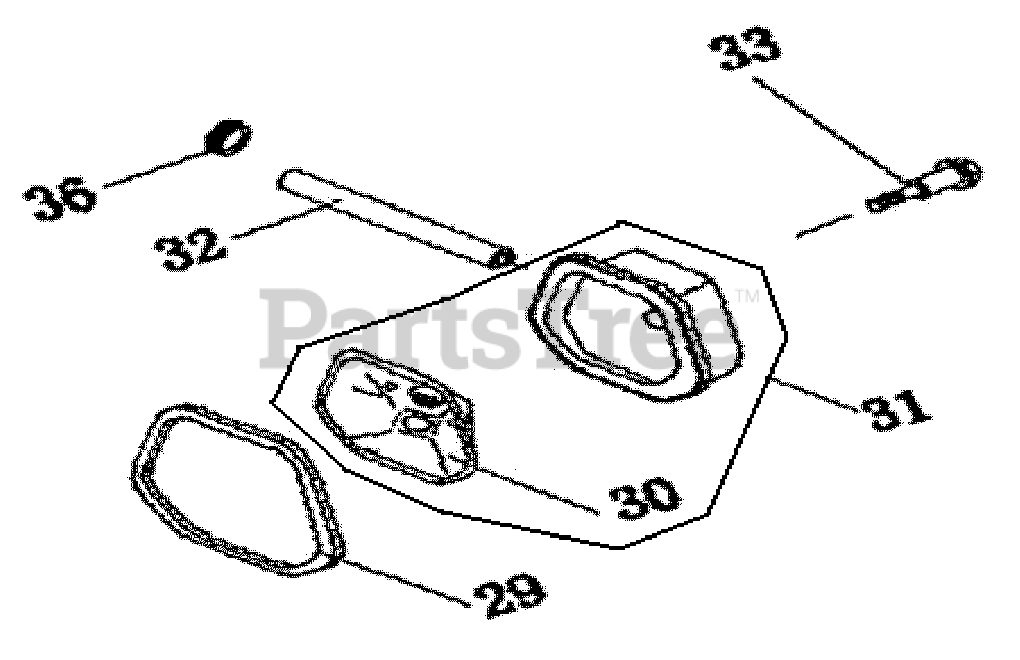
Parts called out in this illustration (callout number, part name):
30	Inside shield
31	Cylinder head cover
32	Gas pipe
36	Rubber band
